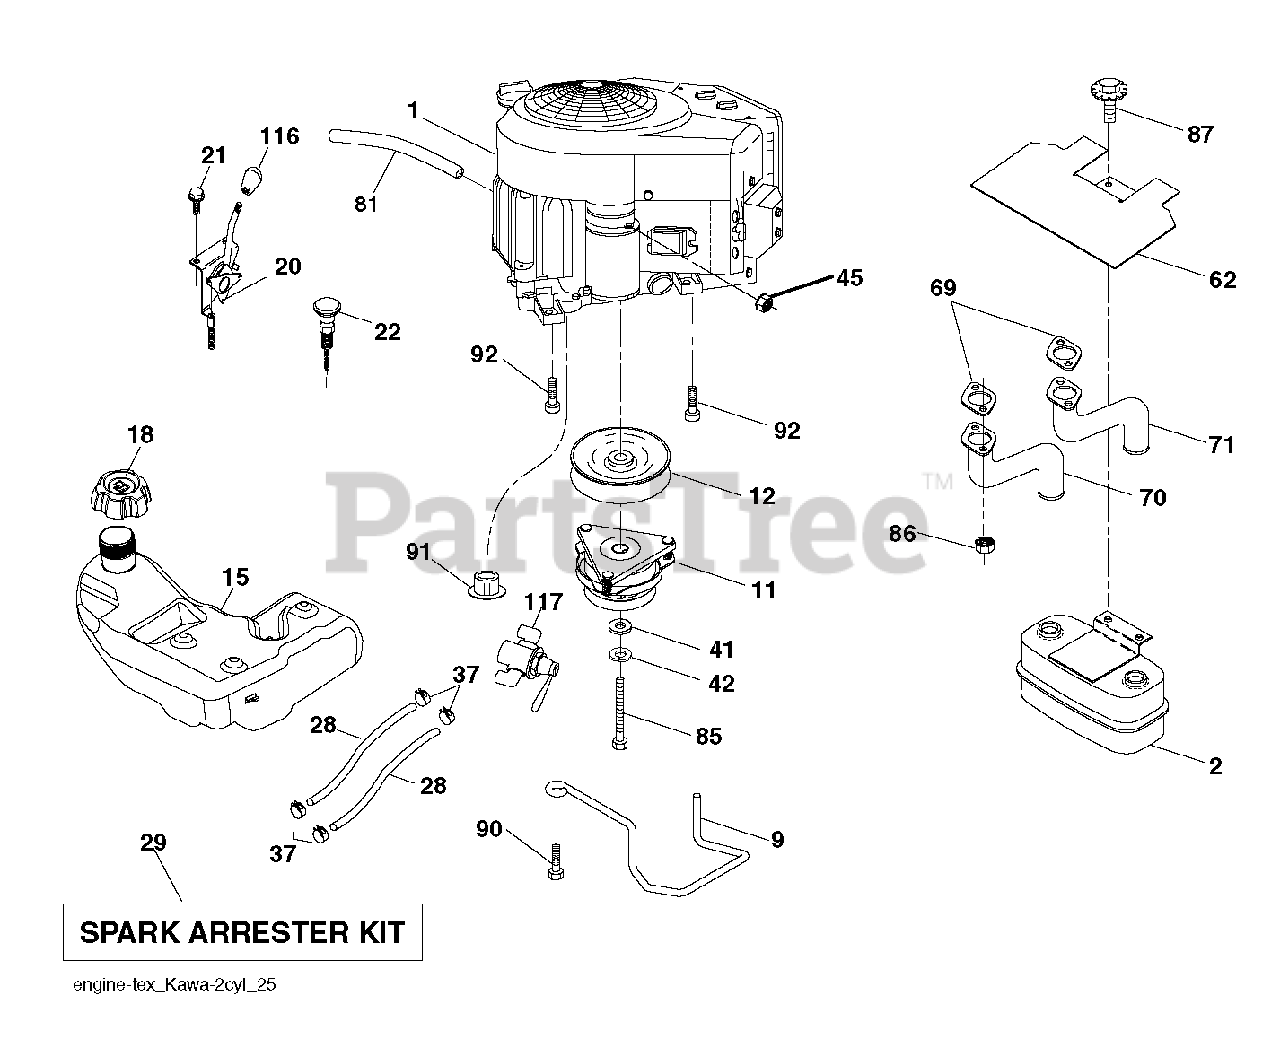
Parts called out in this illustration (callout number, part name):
2	MUFFLER.ASM.TWN.EXTNDED.DFLCTR
9	KEEPER BELT ENGINE
11	CLUTCH MZ ZTR GT.48/54"1.125"
12	PULLEY ENGINE
15	TANK.ASSY.4.GAL.2.PORT.EPA
18	RP CAP FUEL
20	CONTROL.THROTTLE.PRO.
21	SCREW.#10 X 0.750.BOS
22	CONTROL.CHOKE.ERGO.PUSH-IN.BLA
28	LINE.FUEL.64"REAR.EMIS
29	KIT.SPARK ARRESTOR 794945 B&S
37	HOSE CLAMP
42	LOCKWASHER
45	NUT
62	SHIELD.HEAT.MUFFLER
70	TUBE.EXHAUST.LH.FR961/FR730
71	TUBE.EXHAUST.RH.FR961/FR730
81	TUBE, DRAIN OIL ASM.
85	BOLT HEX 7/16-20 X 3.75 GR. 5
86	NUT.HEX.FLANGE.TOPLOCK
87	BOLT, 5/16-18 X 1 3/4
90	SCREW 3/8-16X1
91	BUSHING.1.375OD
92	SCREW 3/8-16X1
116	RP KNOB SOFT TOUCH
117	VALVE FUEL RESERVE
